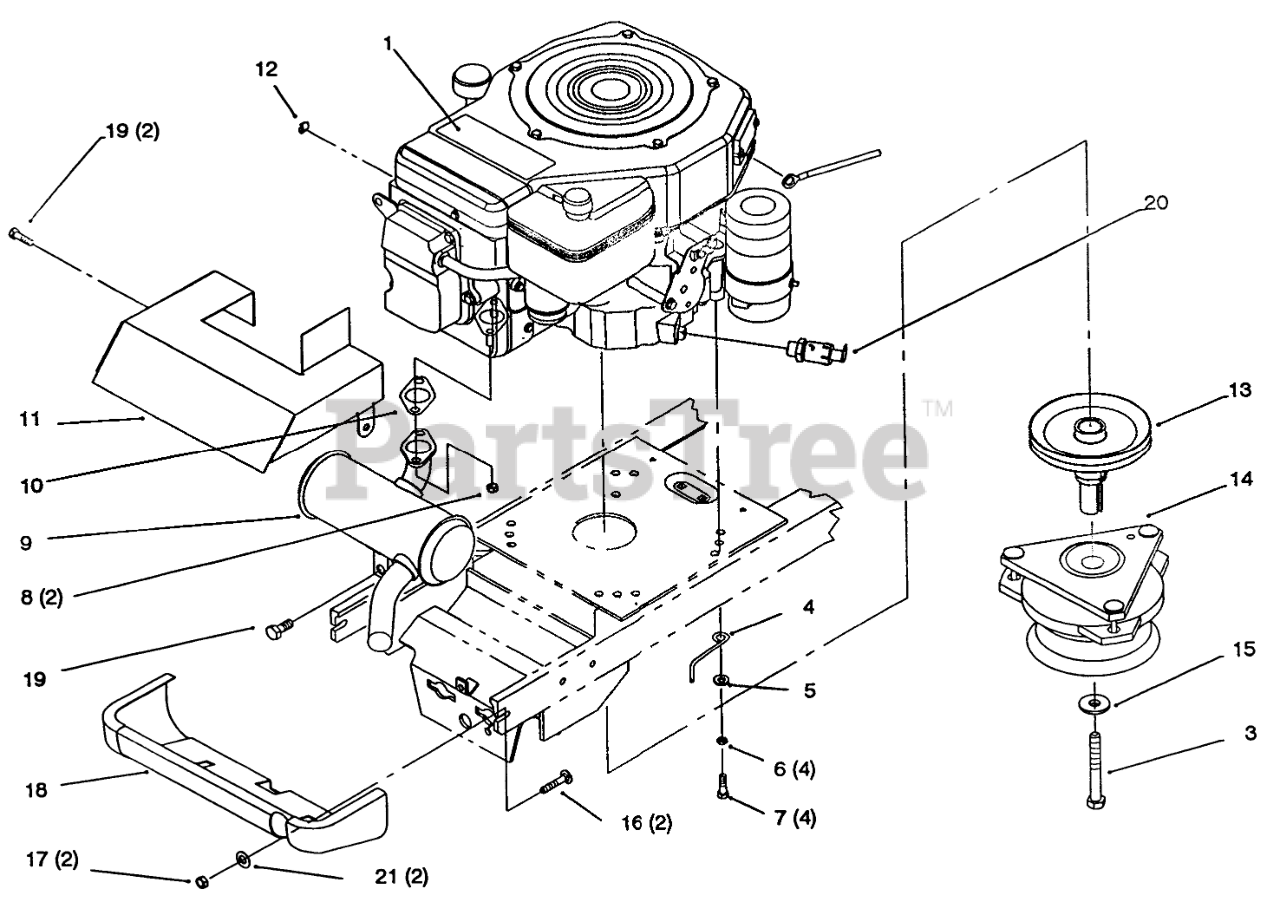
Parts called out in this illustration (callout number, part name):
1	Decal-Toro Power Plus 14 (Only On: 72042 72062, 72043, 72063)
3	Screw-HH (Only On 72043, 72042, 72063 72062)
4	Guide-Belt (Only On: 72042,72062)
5	Washer-Flat (Only On: 72042,72062)
6	Washer-Lock (Only On: 72043, 72042, 72063, 72062)
7	Screw-HH (Only On: 72043, 72042, 72063, 72062)
8	Nut-HHF (Only On: 72043, 72042, 72063, 72062)
9	Muffler (Only On: 72043, 72042,72063, 72062)
10	Gasket-Exhaust (Only On: 72043, 72042, 72063, 72062)
11	Baffle-Muffler (Only On: 72043,72042, 72063, 72062)
12	Clip-Wire Retainer (Only On: 72043, 72042, 72063, 72062)
13	Pulley (Only On: 72043, 72063)
13	Pulley-Engine (Only On: 72042,72062)
14	Clutch-PTO (Only On: 72043,72042, 72063, 72062)
15	Washer-PTO (Only On: 72043,72042, 72063, 72062)
16	Bolt-CARR (Only On: 72043,72042, 72063, 72062)
17	Nut-Hex Lock (Only On: 72043,72042,72063, 72062)
18	Shield-Muffler (Only On: 72043,72042, 72063, 72062)
19	Screw-HWHTF (Only On: 72043, 72042, 72063, 72062)
20	Valve-Oil Drain (Only On: 72043,72042, 72063, 72062)
21	Washer-Flat (Only On: 72043,72042, 72063, 72062)
